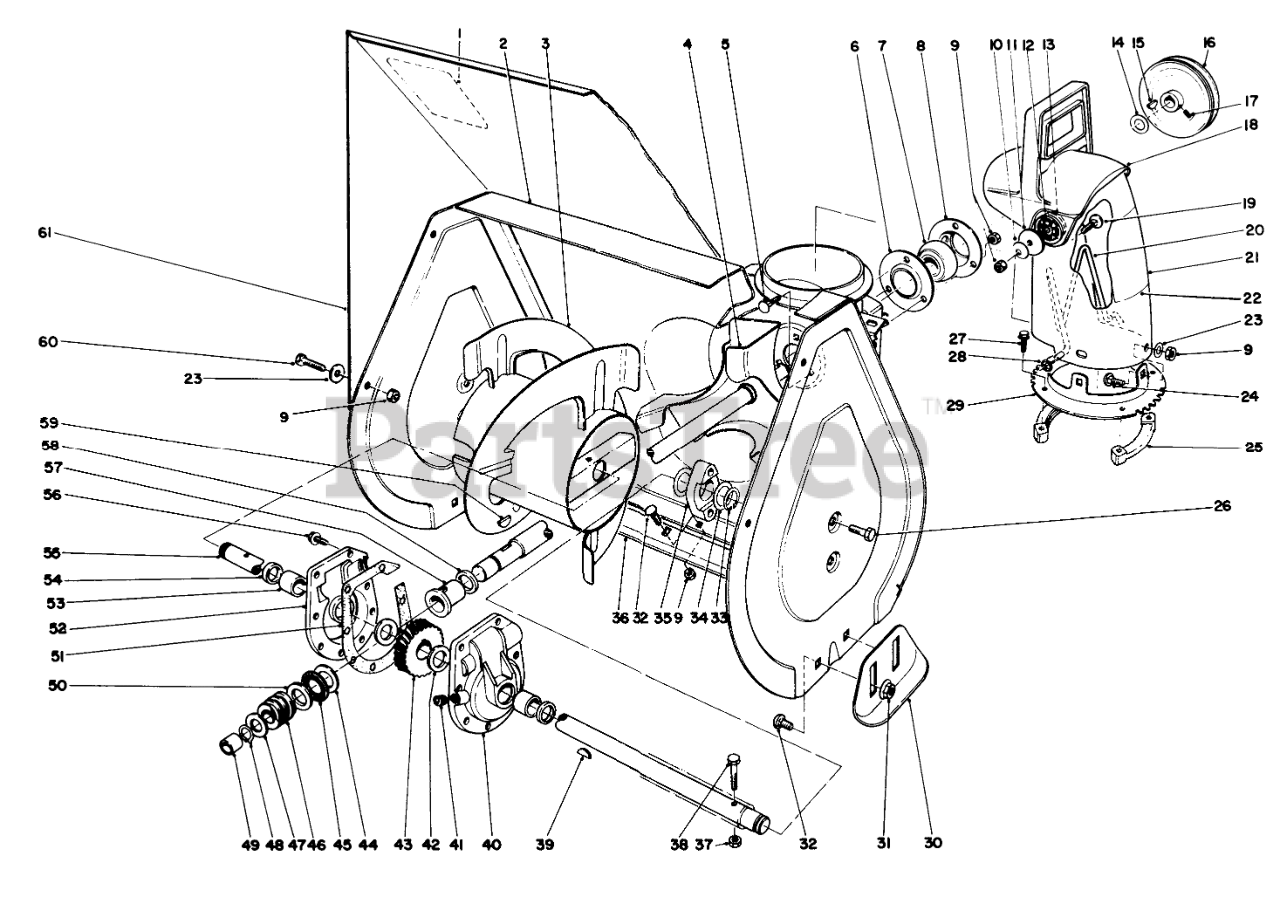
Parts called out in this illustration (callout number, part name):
1	DECAL-WARNING, AUGER
2	Housing-Auger (Incl. Ref. #1)
3	Auger R.H.
4	Shaft & Impeiler
5	SCREW-CARR
6	Bearing Flange-Front
7	BEARING-BALL
8	Bearing Flange-Rear
9	NUT-LOCK, NI
10	WASHER-BELLEVILLE
11	WASHER-FLAT
12	PLATE-FRICTION
13	WASHER-RUBBER
14	WASHER
15	KEY-WOODRUFF
16	PULLEY
17	SCREW-SET, SQH
18	CHUTE-DEFLECTOR
19	SCREW-CARR
20	WIRE-CHUTE
21	Chute-Discharge
22	Decal-Danger
23	WASHER-PLAIN
24	SCREW-CARR
25	RING-CHUTE, RETAINER
26	SCREW-HWHTF
27	SCREW-SPECIAL
28	NUT-PUSH
29	Chute Ring
30	Skid
31	NUT-HF
32	BOLT-CARR
33	RING-RETAINING
34	WASHER
35	BEARING-AUGER
36	Blade-Scraper
37	NUT-LOCK, NI
38	SCREW-HH
39	KEY-WOODRUFF
40	Gear Case L.H. (Incl. Ref. #53 & 54)
41	PLUG-PIPE, SQH
42	WASHER-THRUST
43	Gear
44	WASHER-THRUST
45	BEARING-THRUST
47	WASHER-THRUST
48	Ring-Snap
49	BUSHING
50	WASHER-THRUST
51	GASKET-CASE, GEAR
52	Gear Case R.H. (Incl. Ref. #53 & 54)
53	BUSHING
54	SEAL-OIL
55	AUGER SHAFT
56	SCREW-TAPTITE
57	BUSHING-INPUT
58	RING-QUAD
59	KEY-WOODRUFF
60	SCREW-HH
61	AUGER EXT 21 SCAND
